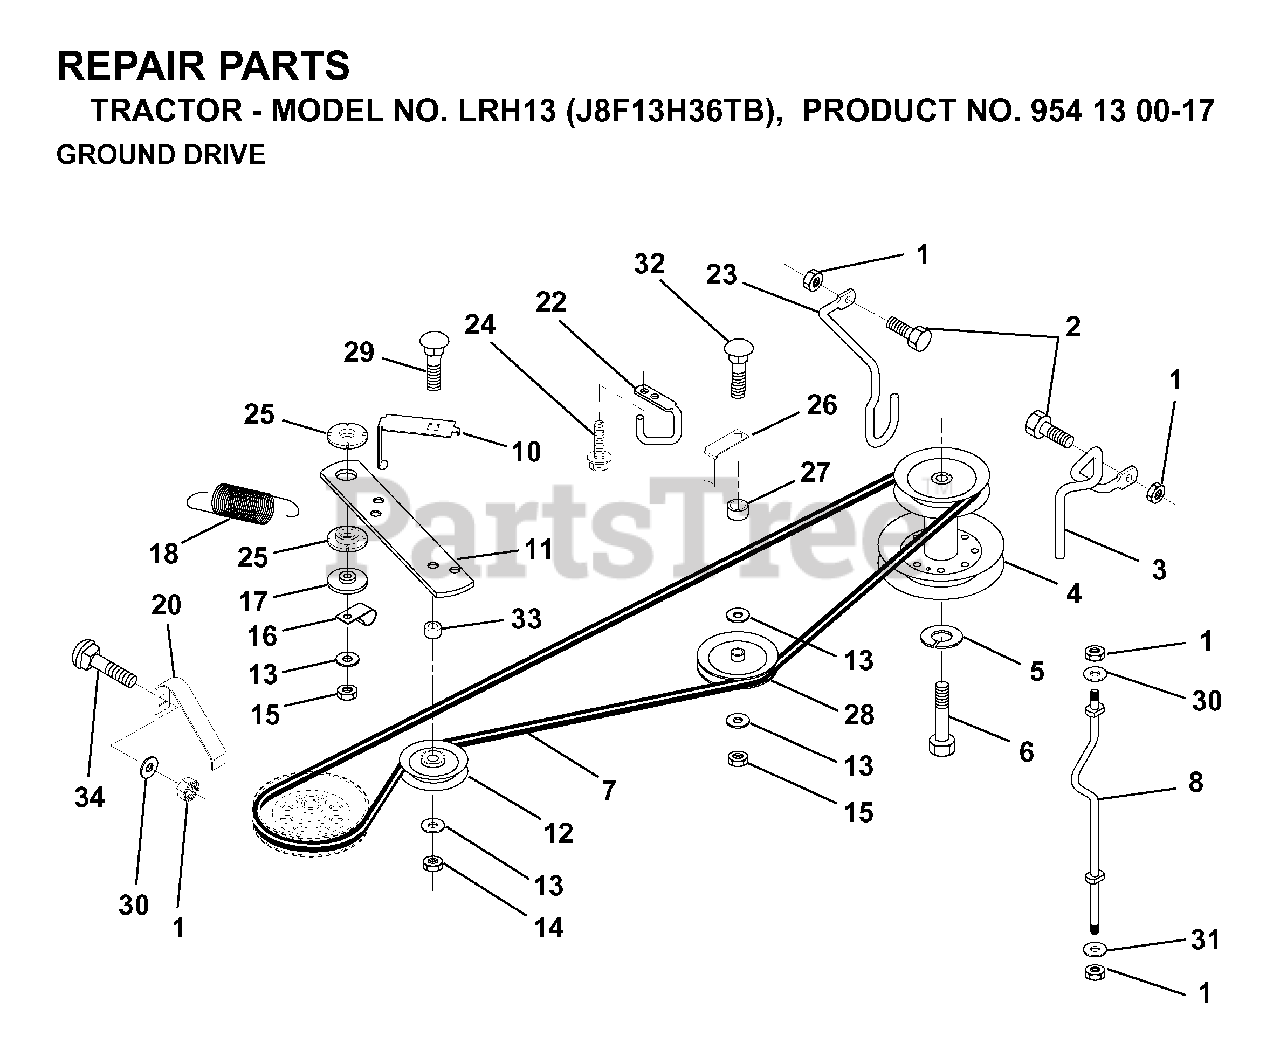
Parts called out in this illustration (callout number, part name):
1	NUT.71038.31-18.HEX.NYLOCK
2	BOLT
4	ENGINE PULLEY
5	LOCKWASHER
10	KEEPER, BELT
11	ARM, GROUND DRIVE CLUTCH
12	PULLEY.IDLER.FLAT
14	LOCKNUT
15	LOCKNUT
16	CLIP,INSULATOR
17	SPACER, RETAINER
18	SPRING.EXTENSION
20	KEEPER, BELT
22	KEEPER,FRA DR BEL
23	KEEPER-MOWER DRIVE LH
24	SCREW
25	BUSHING NYLON COLLERED
26	KEEPER, BELT
28	PULLEY.IDLER.V.
29	BOLT
30	WASHER
31	WASHER M
32	BOLT
33	SPACER NLA
34	BOLT
